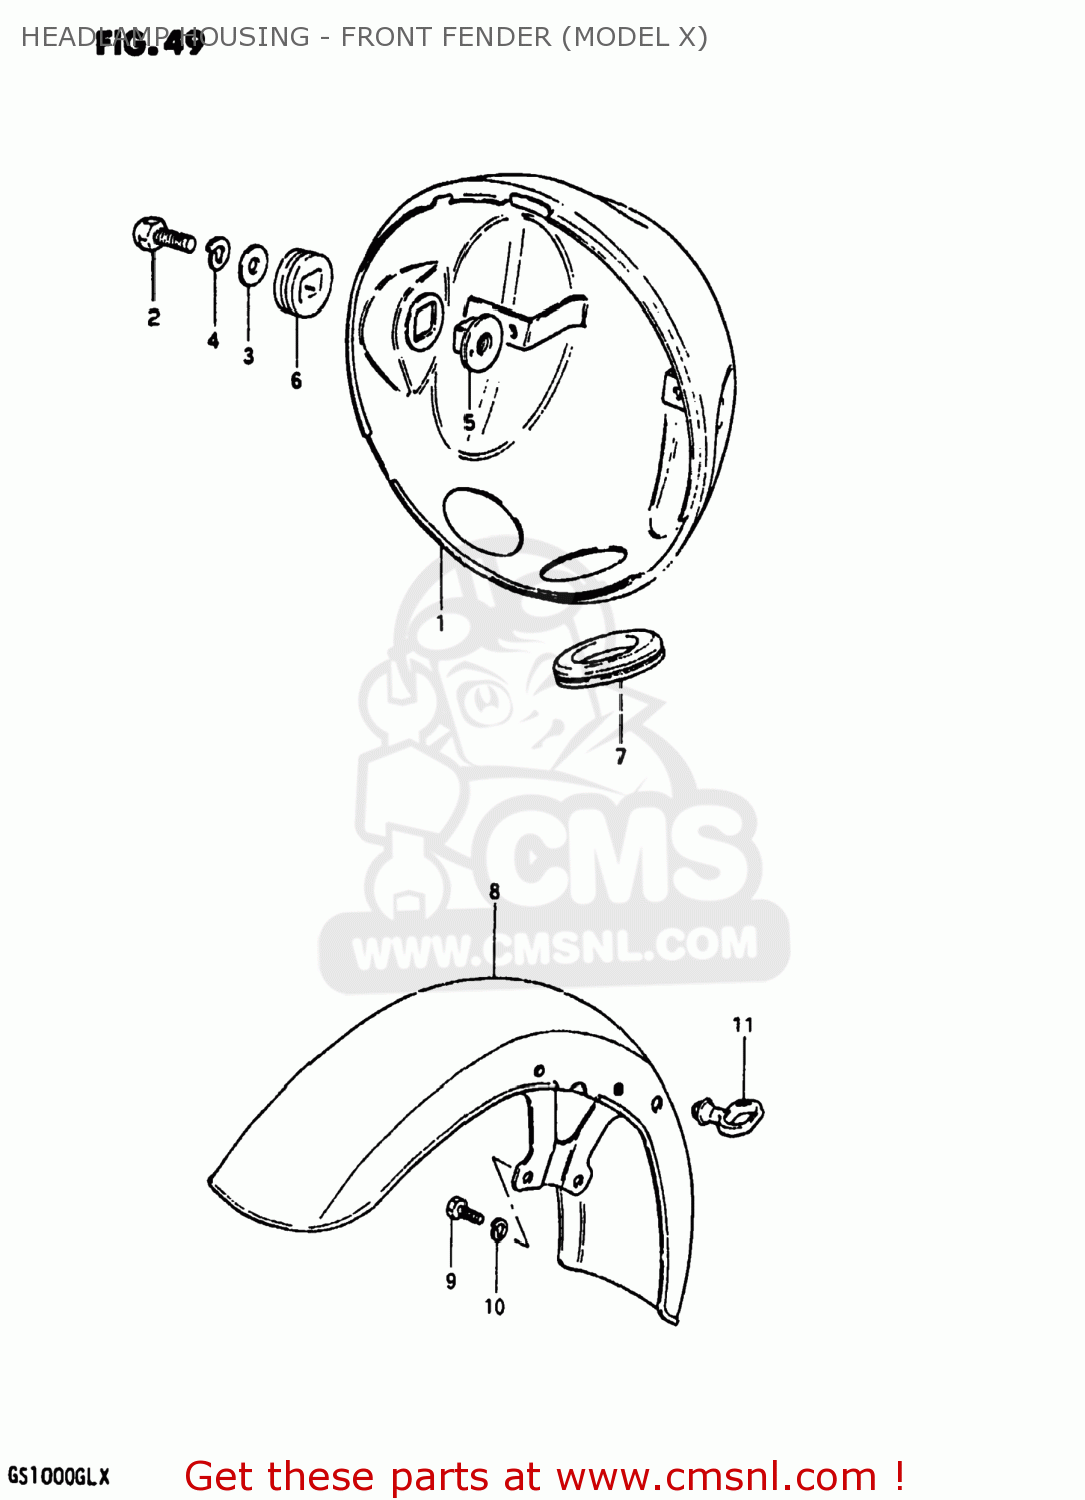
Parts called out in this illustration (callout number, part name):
1	HOUSING,HEADLAMP
2	BOLT
3	WASHER
4	LOCK WASHER
5	SPACER,HEADLAMP HOUSING
6	CUSHION,HEADLAMP HOUSING
7	GROMMET,HEADLAMP HOUSING
8	FENDER,FRONT
9	BOLT
10	LOCK WASHER
11	GUIDE,CABLE
